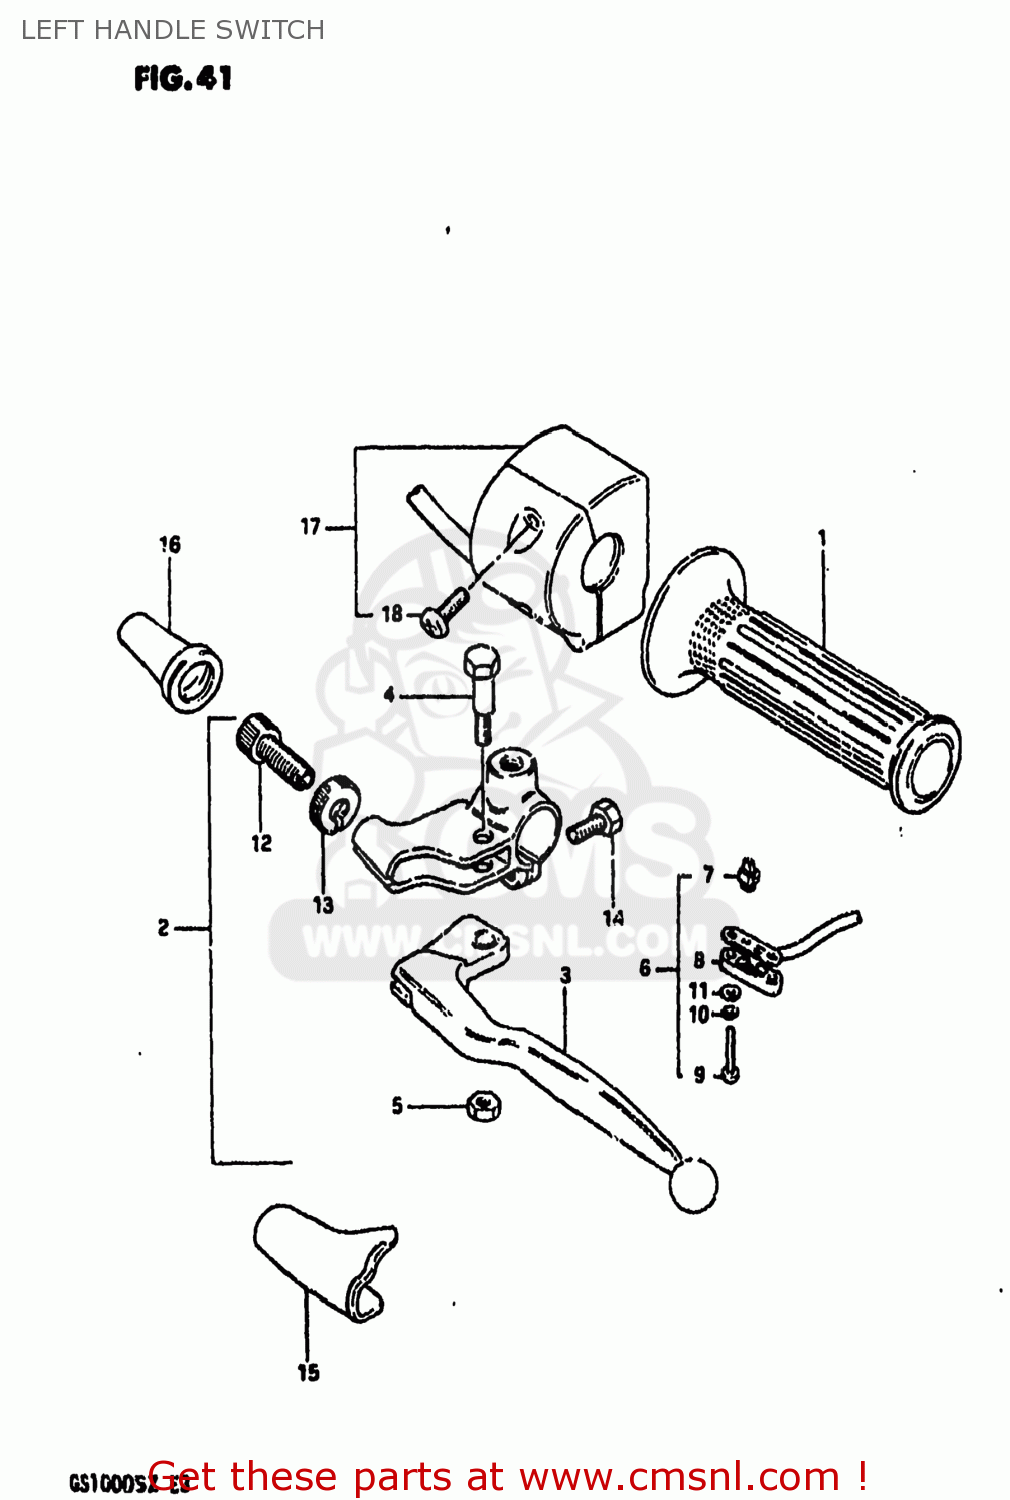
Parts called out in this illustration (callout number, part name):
1	GRIP,LEFT
2	LEVER ASSEMBLY
3	LEVER,CLUTCH
4	BOLT,LEVER
5	NUT 6MM
6	WIRE HARNESS,CLUTCH SWITCH
7	CONTACT,SWITCH
8	COVER,FR BK TERMINAL BASE
9	SCREW
10	LOCK WASHER
11	WASHER
12	ADJUSTER,CABLE
13	NUT,CABLE ADJUSTER
14	BOLT,CLUTCH LEVER HOLDER
15	COVER,CLUTCH LEVER
16	BOOT,CLUTCH CABLE
17	SWITCH ASSY,HANDLE,L
18	SCREW
19	BUTTON,STARTER
20	SPRING,STARTER BUTTON
21	CONTACT,STARTER BUTTON
